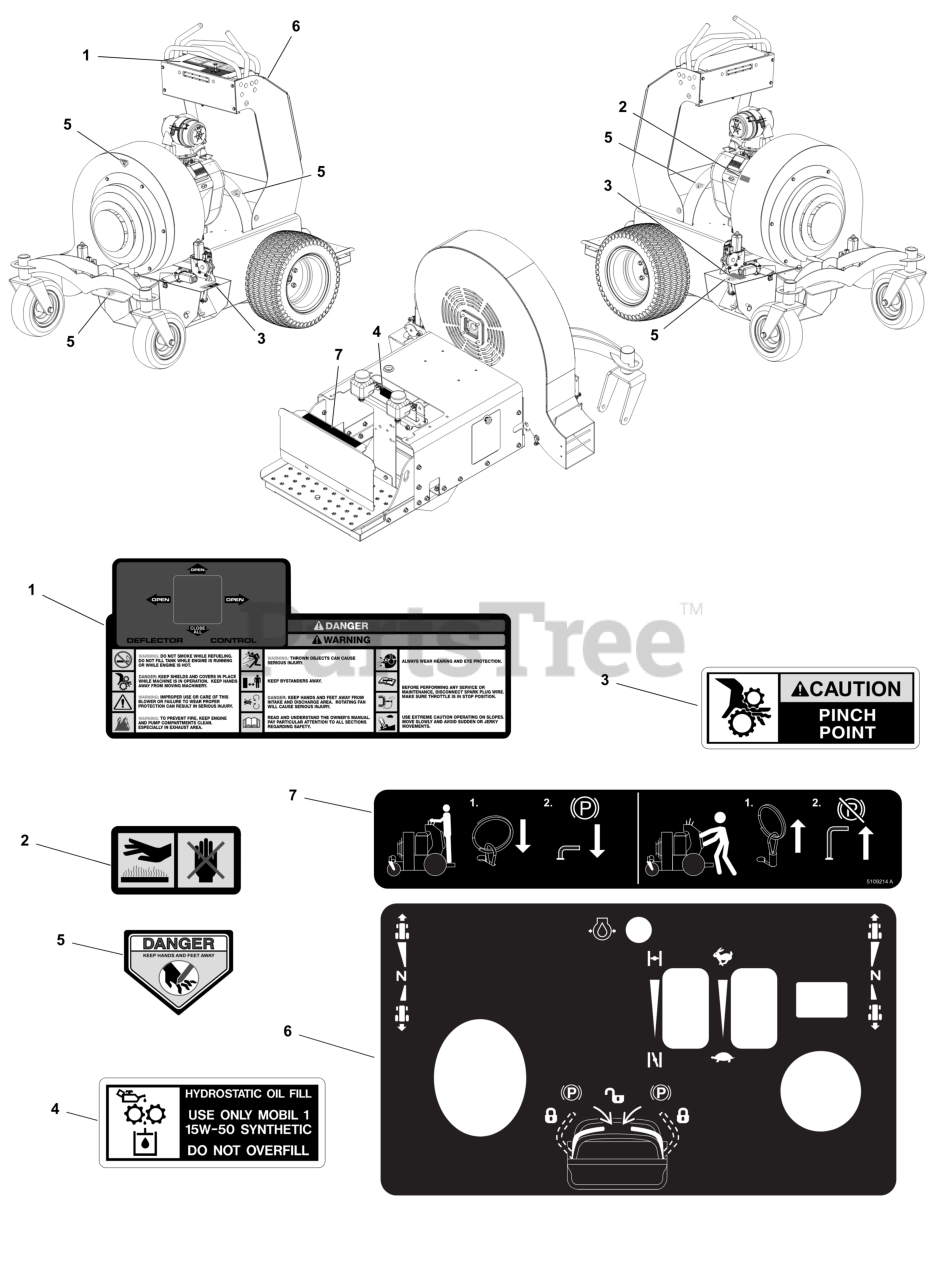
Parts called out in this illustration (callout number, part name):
1	DECAL, CONTROLS
2	DECAL, WARNING, HOT SURFACE
3	DECAL, Warning/Safety
6	DECAL, Controls
7	DECAL, BRAKE, PARK
